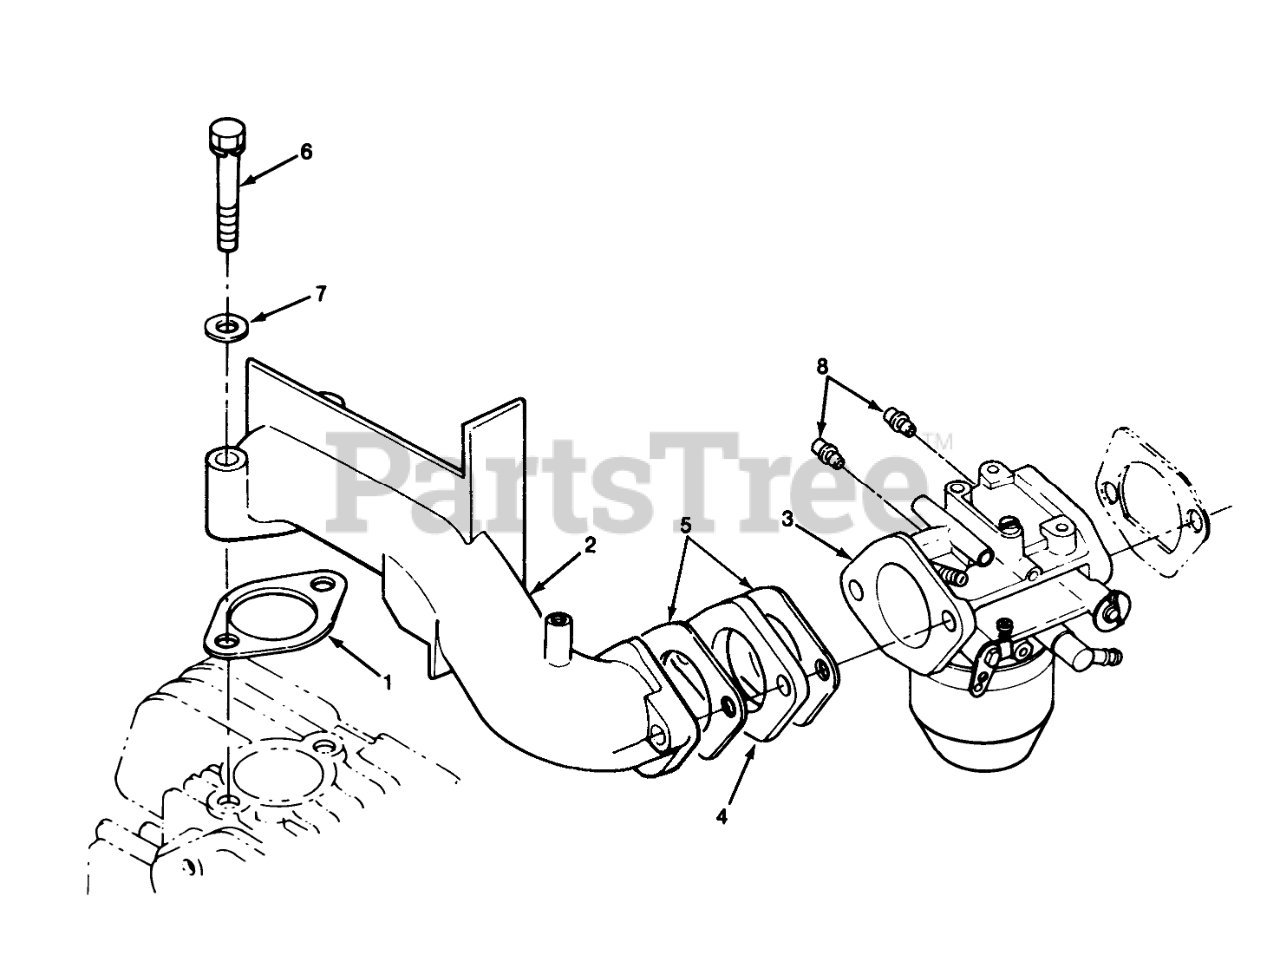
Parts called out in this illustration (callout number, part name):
1	Gasket
2	ELBOW-INTAKE
3	CARBURETOR
4	INSULATOR
5	Gasket
6	HHCS-M8 X 50MM
7	Nut-M8
8	Clip
